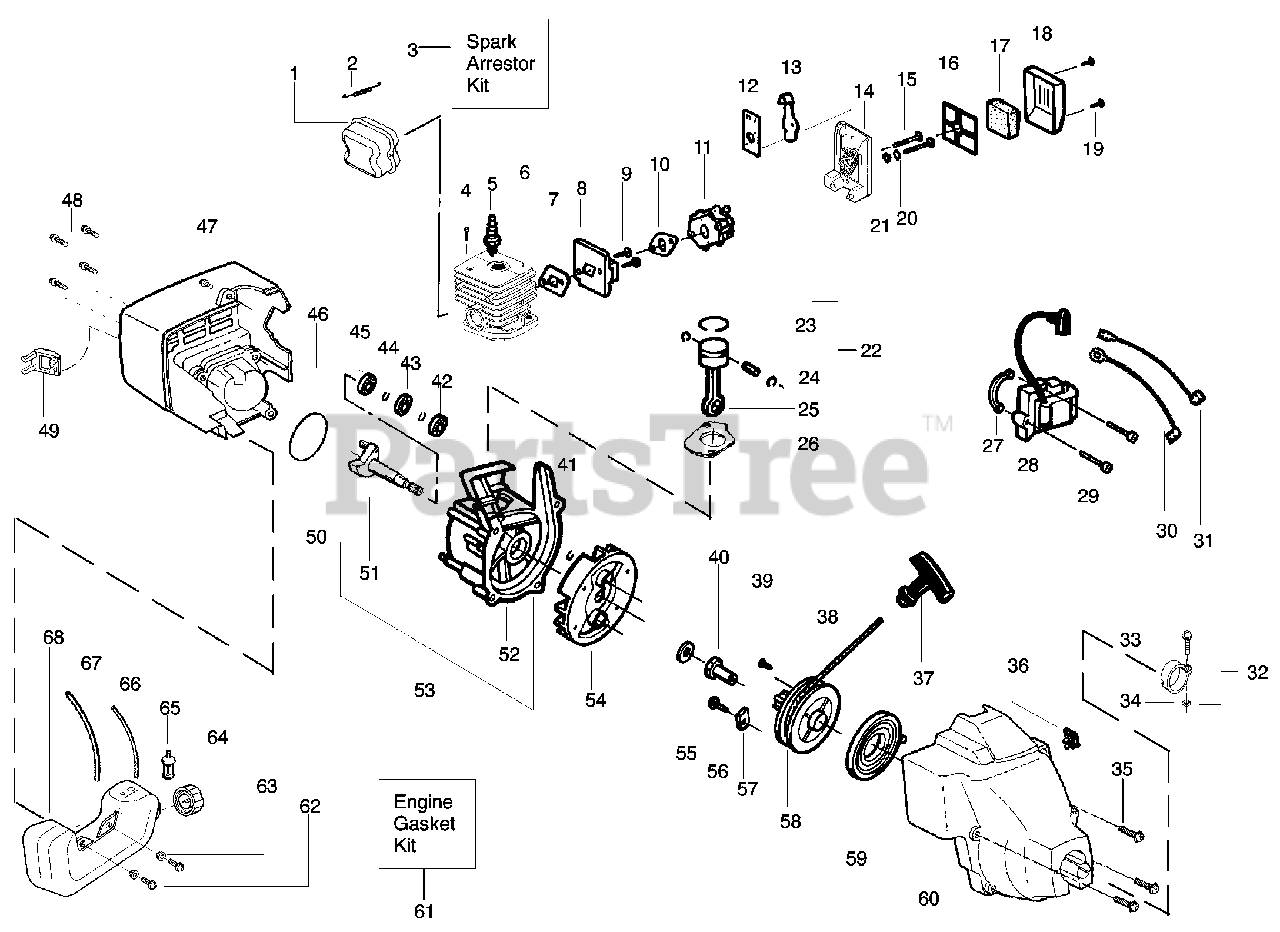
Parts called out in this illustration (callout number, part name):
1	Kit - Muffler
2	Spring-Muffler
3	Kit-Spark Arrestor
4	Screw-Cylinder
5	Spark Plug (RCJ 8Y)
6	Kit - Cylinder
7	Gasket-Cyl/Carb.(kit)
8	Kit - Carb. Adaptor
10	Gasket-Carb.(kit)
11	Kit - Carburetor Ass'y
12	Plate-Choke Mounting
13	Shutter-Choke
16	Plate - Filter Support
17	Foam-Air Filter
18	Cover-Air Filter
20	Spacer-Choke
22	Kit - Piston
23	Ring-Piston
24	Retainer-Piston Pin
25	Assy-Connecting Rod
26	Gasket-Cylinder (kit)
27	Spacer-Module
28	Module-Ignition
30	Assy-Ground Wire
31	Assy-Leadwire
32	Assy-Nose Cone Clamp
33	Screw-Nose Cone
34	Nut-Nose Cone
35	Screw
36	Kit-Momentary Switch
37	Handle-Starter
38	Kit - Rope
40	Coupling-Drive
41	Retain. Ring-C'shaft
42	Bearing-Outer
43	Seal-C'case
44	Retainer Ring-C'case
45	Bearing-Inner
46	Shroud-Rear
48	Screw
49	Guard-Muffler
50	O-Ring-C'case (kit)
51	Assy-Crankshaft
52	Assy-Crankcase
53	Assy-C'case & C'shaft
54	Assy-Flywheel
55	Washer-Flat
57	Retainer
58	Kit-Starter Pulley
59	Spring-Starter
60	Kit-Fan Hsg. Assy.
61	Kit-Engine Gasket
64	Assy-Fuel Cap w/ret.
65	Assy-Fuel Pickup
66	Kit-Fuel Line (Small)
67	Kit-Fuel Line (Large)
68	Assy-Fuel Tank
